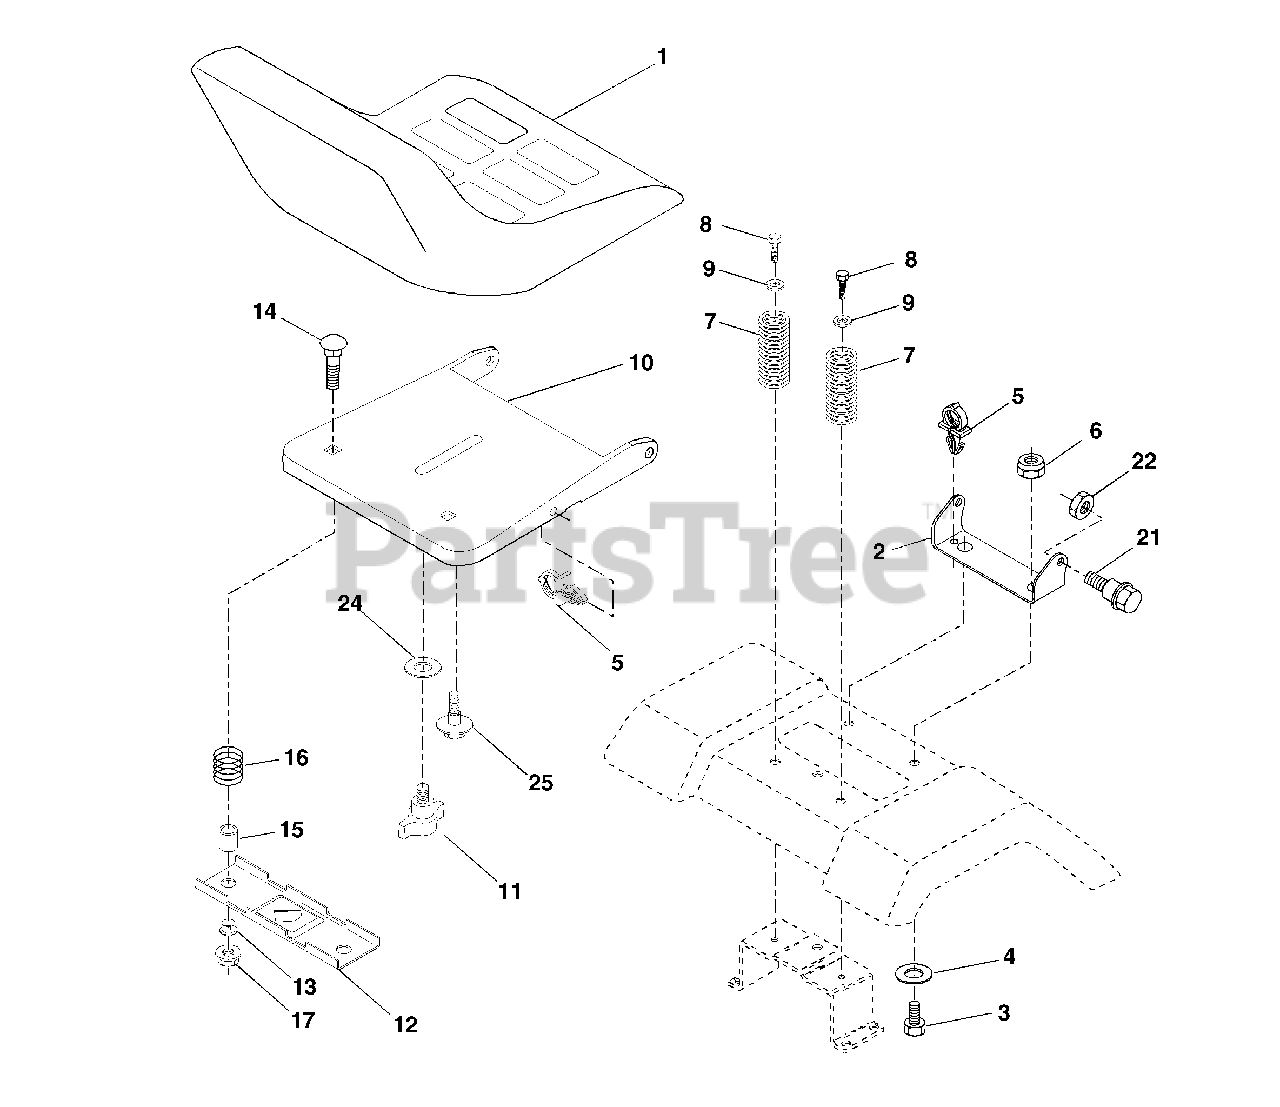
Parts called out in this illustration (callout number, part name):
1	Seat
2	Bracket Pivot Seat 8 720
3	Bolt Fin Hex 3/8-16 x 1
4	Washer Flat 13/32 x 1.0 x 10 Ga.
5	Clip Push-In
6	Nut Hex w/Ins. 3/8-16 Unc
7	Spring Seat Cprsn 2 250 Blk Zi
8	Screw 3/8-16 x 1
9	Washer 13/32 x 1.0 x 14 Ga.
10	Pan Seat
11	Knob Seat Adj Wingnut
12	Bracket Mounting Switch
13	Bushing Snap Blk Nyl 50 Id
14	Bolt Rdhd Sqnk 1/4-20x1-1/2
15	Spacer Split 28 x .88 Zinc
16	Spring Cprsn Plate
17	Nut Lock 1/4 Lge Flg Gr 5 Zinc
21	Bolt Shoulder 5/16-18 Unc
22	Nut Hex Lock W/Ins 5/16-18
24	Washer 17/32 X 1 -3/16 X 12 Ga.
25	Bolt Shoulder 5/16-18 X 62
